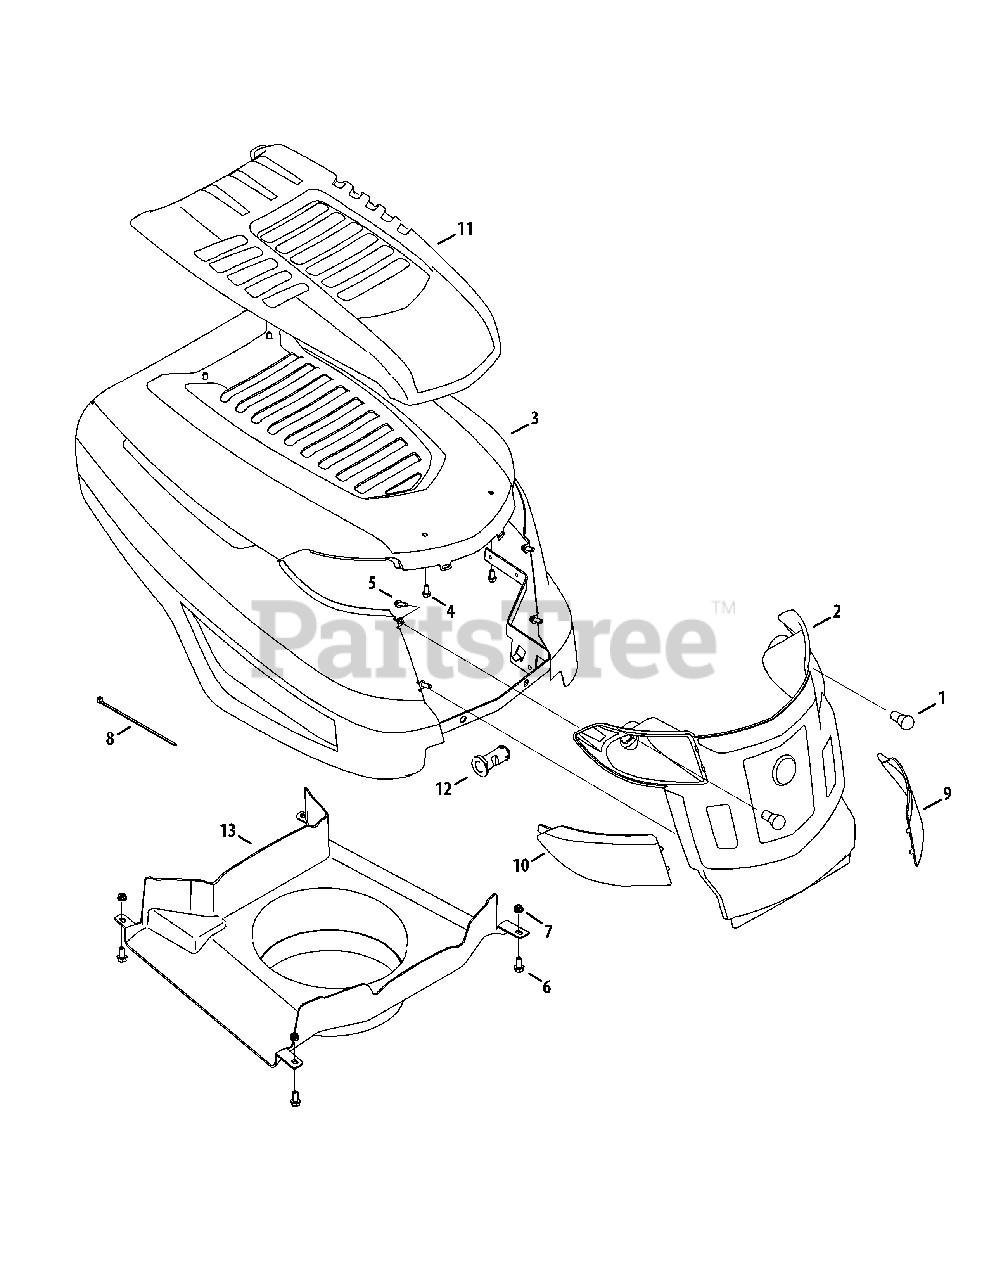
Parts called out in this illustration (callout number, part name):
1	Miniature lamp 12V socket
2	Grill
4	Screw, 1/4-15 x 0.50
5	Screw, 1/4 x .750
6	Hex Cap Screw, 1/4-20 x .62
7	Nut, Flange Lock, 1/4-20, Nylon
8	Cable Tie
9	Grill Lens - LH
10	Grill Lens - RH
11	Hood Scoop
12	Hood Pin
13	Plenum
